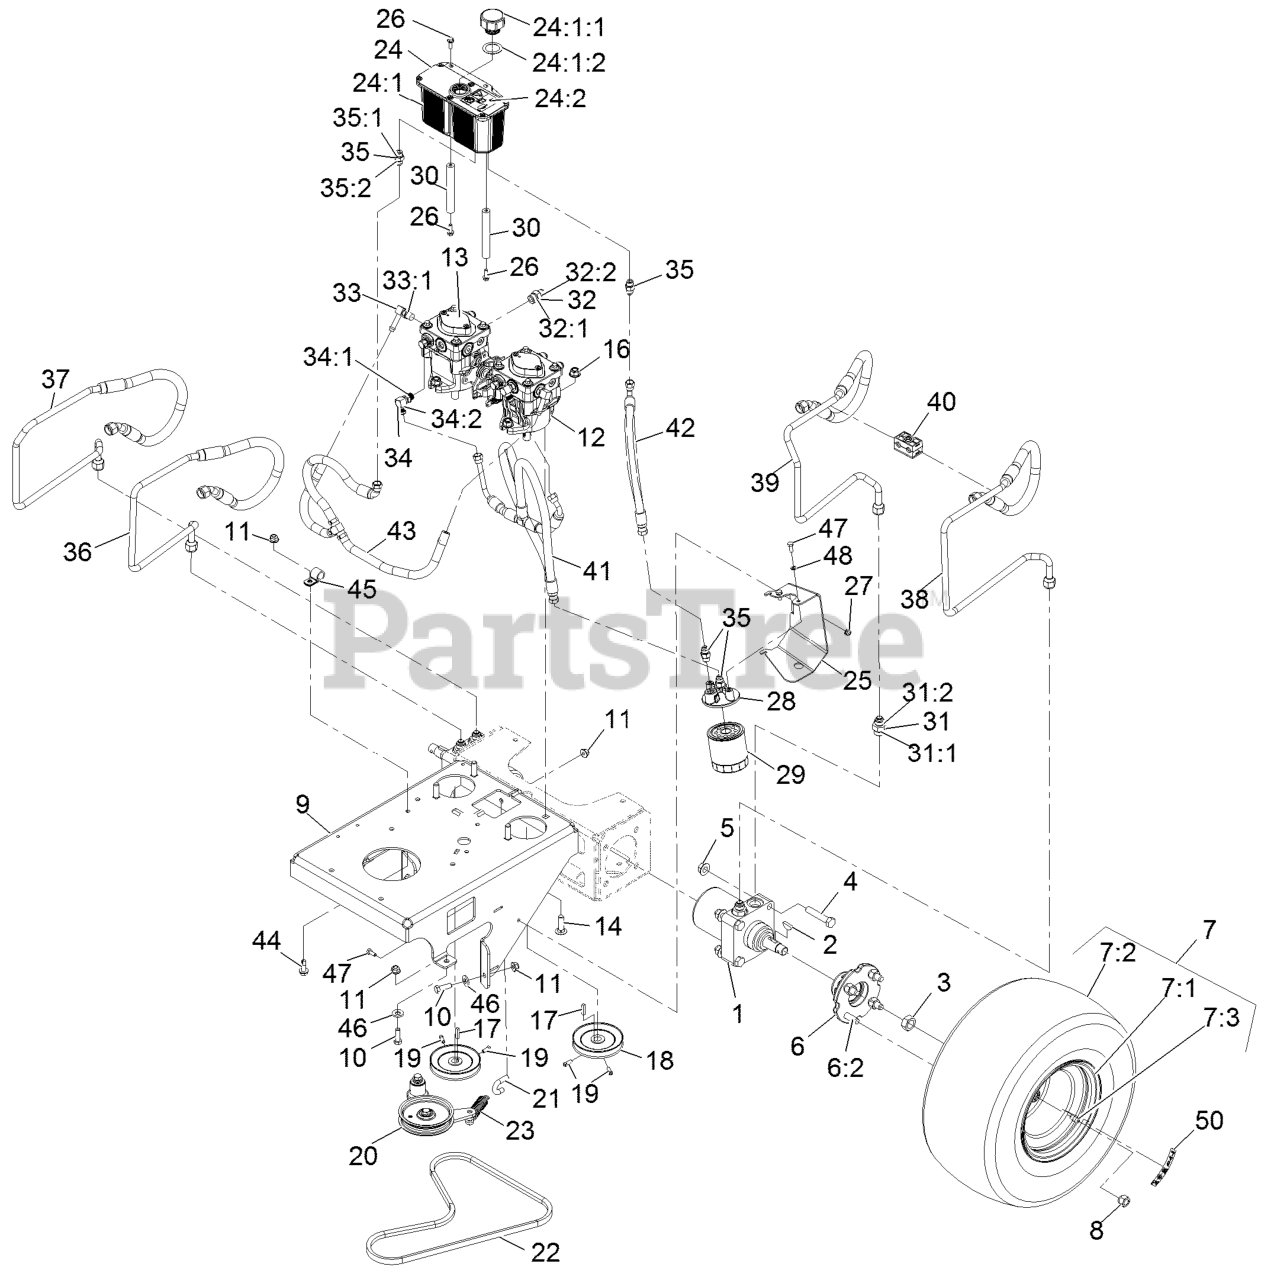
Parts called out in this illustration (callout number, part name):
1	HYD MOTOR ASM
2	KEY-WOODRUFF
3	NUT-MOTOR, WHEEL
4	SCREW-HH
6	WHEEL HUB ASM
6:2	STUD-TYPE, DRIVE
7	WHEEL/TIRE ASM
7:1	RIM-8 INCH
7:3	Stem-Valve
8	NUT-LUG
9	BASE, ENGINE
10	SCREW-HH
11	NUT-HF, NI
12	PUMP - HYDRAULIC
13	PUMP-HYDRAULIC
14	SCREW-HH
16	NUT-HF, NI
18	PULLEY-PUMP
19	SCREW-SET
20	PUMP IDLER ASM
21	ANCHOR, SPRING
22	BELT-V
23	SPRING-EXTENSION
24	RESERVOIR ASM
24:1	Reservoir-HYD
24:1:1	Cap-Reservoir, HYD
24:1:2	GASKET-CAP
24:2	DECAL-WARNING
25	PLATE-FILTER MOUNT
26	SCREW-HHF
28	HEAD-FILTER
29	FILTER-25 MICRON, BI-DIRE
30	ROD-RESERVOIR STAND
31	FITTING-STRAIGHT
31:1	O-RING
32	FITTING-STRAIGHT
33	FITTING-ELBOW, 90
33:1	O-RING
34	FITTING-90 DEG
35	FITTING-STRAIGHT
36	HOSE-HARDLINE
37	HOSE-HARDLINE
38	HOSE-HARDLINE
39	HOSE-HARDLINE
40	CLAMP, STAUFF 212,7/12,7
41	HOSE-ASM CHARGE
42	HOSE ASM-HYD LP 3/8X14.4
43	HOSE ASM - HYD 3/8
44	SCREW-TAPPING
45	CLIP-LOOM
46	WASHER-BELLEVILLE
47	SCREW-HH
48	WASHER-LOCK
50	DECAL-WHEEL TORQUE
